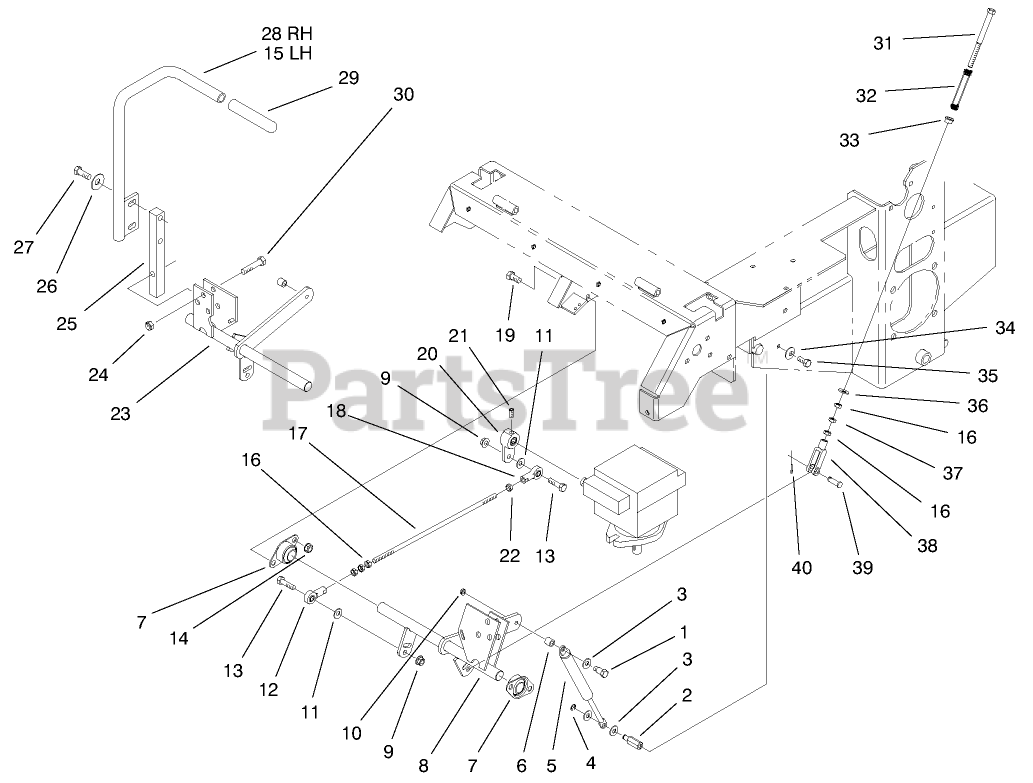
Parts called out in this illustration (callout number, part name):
1	Screw-HSH
2	Pin-Damper Anchor
3	WASHER-PLAIN
4	E-Ring
5	Damper
6	Spacer
7	Bearing-Side Flange
8	Bracket-Motion Control, LH
9	NUT-HF
10	NUT-HF
11	WASHER-FLAT
12	Ball Joint
13	SCREW-HH
14	NUT-HHF, WHIZ
15	Lever-LH
16	NUT-HEX
17	Link-Pump Control
18	Ball Joint LH
19	SCREW-HH
20	Arm-Pump Control
21	Screw
22	Nut
23	Bracket-Motion Control, RH
24	NUT-LOCK, NI
25	Arm
26	Washer
27	SCREW-HH
28	Lever-RH
29	Grip
30	SCREW-HH
31	Bolt
32	Spring
33	Bushing
34	Washer-Lock
35	SCREW-HH
36	WASHER-FLAT
37	NUT-JAM
38	Yoke
39	Pin-Clevis
40	PIN-COTTER
